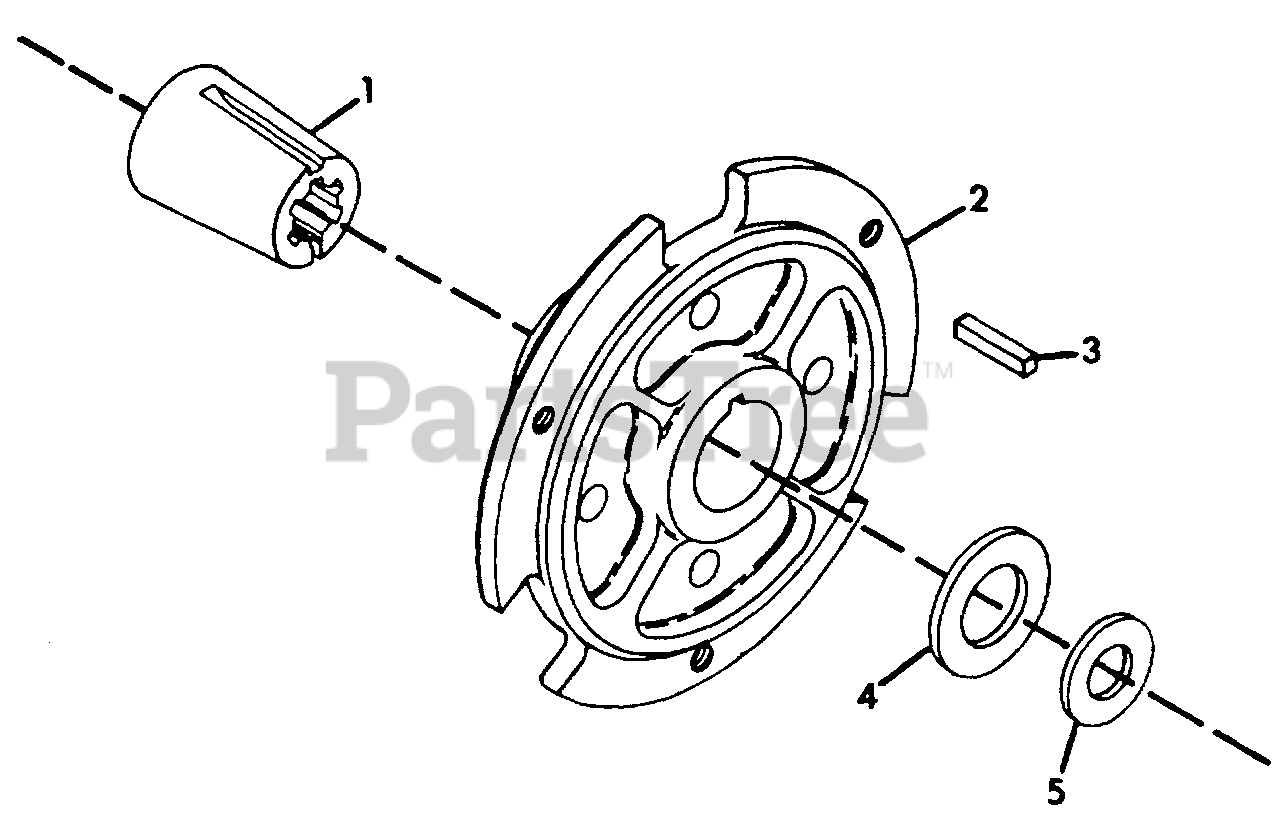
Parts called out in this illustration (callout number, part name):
1	INSERT, HUB
2	HUB, WHEEL
3	KEY, SQUARE .250X1.250
4	WASHER, FLAT HARD
5	WASHER, FLAT .812X1.469X.130
